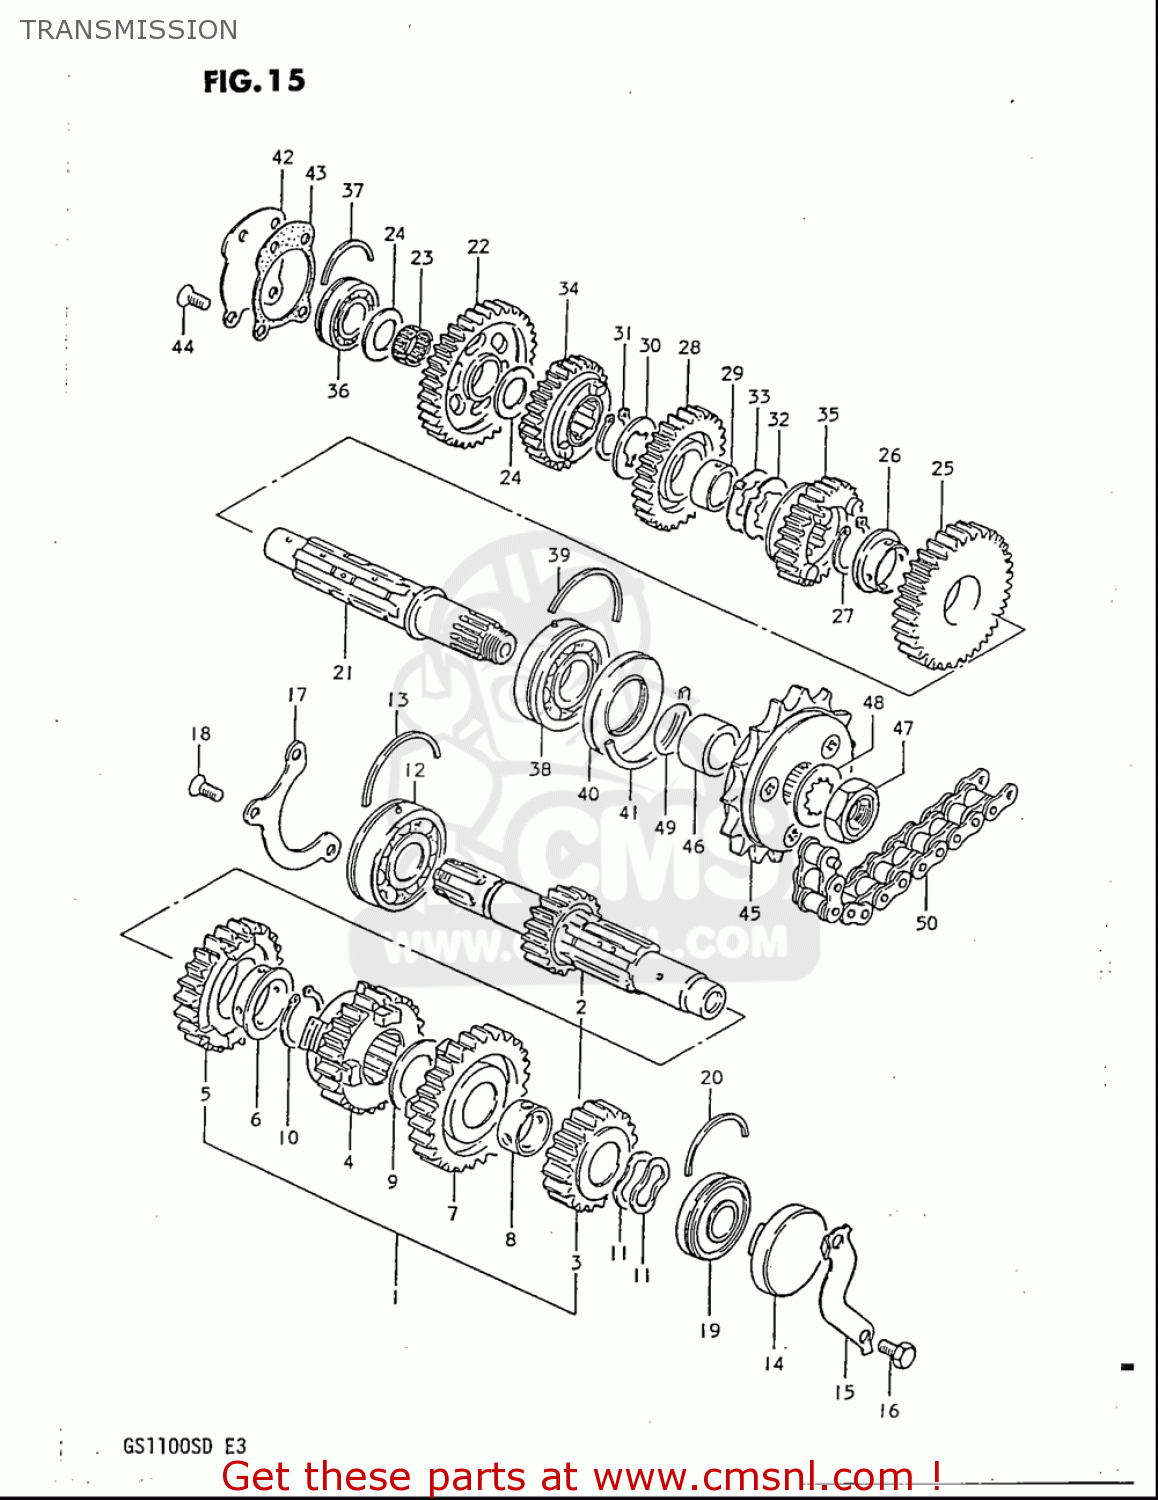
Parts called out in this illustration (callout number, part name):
2	SHAFT,COUNTER (NT:14)
3	GEAR,2ND DRIVE(NT:18)
4	GEAR,3RD DRIVE(NT:21)
5	GEAR,4TH DRIVE(NT:24)
6	BUSH(28X32X2)
7	GEAR,5TH DRIVE(NT:26)
8	BUSH
9	WASHER
10	CIRCLIP
11	WASHER
12	BEARING(25X62X17)
13	C RING
14	PLUG
15	RETAINER,CL PUSH ROD OIL SEAL
16	BOLT
17	RETAINER,CNTR SHAFT BEARING
18	SCREW
19	BEARING(20X47X14)
20	C RING
21	SHAFT,DRIVE
22	GEAR,FIRST DRIVEN (NT:35)
23	BEARING(20X24X10).8
24	WASHER
25	GEAR,2ND DRIVEN(NT:32)
26	BUSH(28X32X2)
27	CIRCLIP
28	GEAR,3RD DRIVEN(NT:29)
29	BUSH,3RD DRIVEN GEAR
30	WASHER,LOCK
31	CIRCLIP
32	WASHER,LOCK
33	WASHER
34	GEAR,4TH DRIVEN(NT:27)
35	GEAR,5TH DRIVEN(NT:25)
36	BEARING(20X47X14)
37	C RING
38	BEARING(25X62X17)
39	C RING
40	SEAL,OIL(32X62X7)
41	C RING
42	PLATE,DRIVE SHAFT
43	GASKET,DRIVE SHAFT PLATE (NAS)
44	SCREW
45	SPROCKET,ENGINE(NT:15)
46	SPACER(25X32X18.6)
47	NUT
48	WASHER,LOCK
49	O RING(D:1,ID:24.5)
50	CHAIN,DRIVE(DID630YL,96LE)
